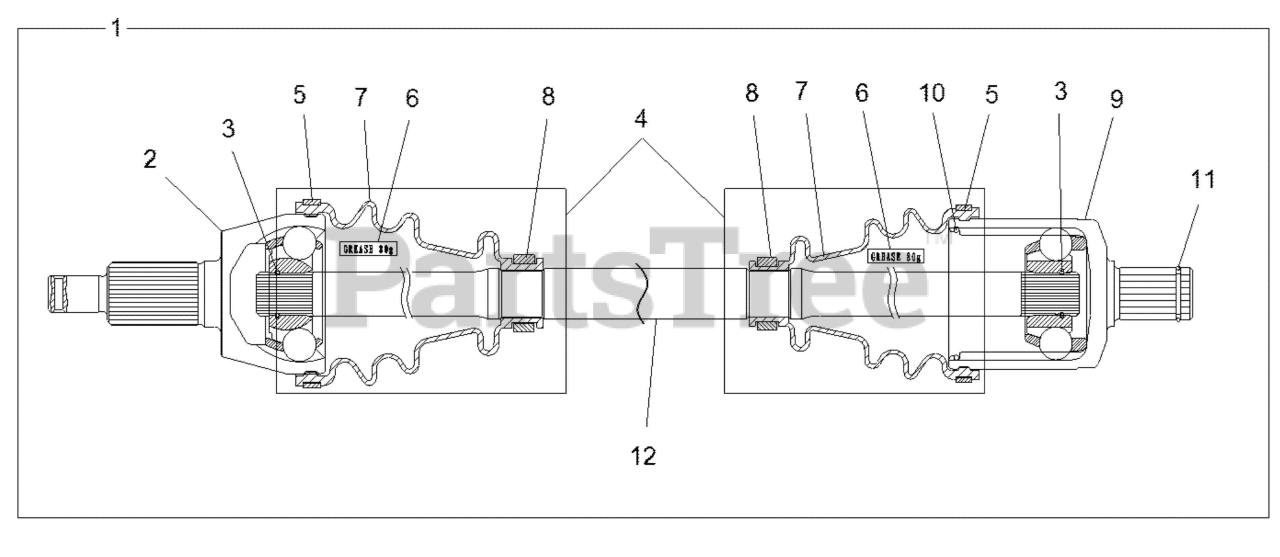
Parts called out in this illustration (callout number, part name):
1	ASM-HALF SHAFT,FRONT,LT
2	JOINT-CV,OUTER
3	CIRCLIP-1.8X22.2(PR-3011)
4	KIT-BOOT,PLUNGING JNT(PR-8062)
5	CLAMP-LARGE(PR-2019)
6	GREASE(K575/VW738)
7	BOOT(PR-0015)
8	CLAMP-SMALL(PR-0016)
9	JOINT-CV,INNER
10	CIRCLIP-2.0X61.7(PR-2016)
11	CIRCLIP-1.6X24.4(PR-2025)
12	SHAFT,23.5(PR-315)
